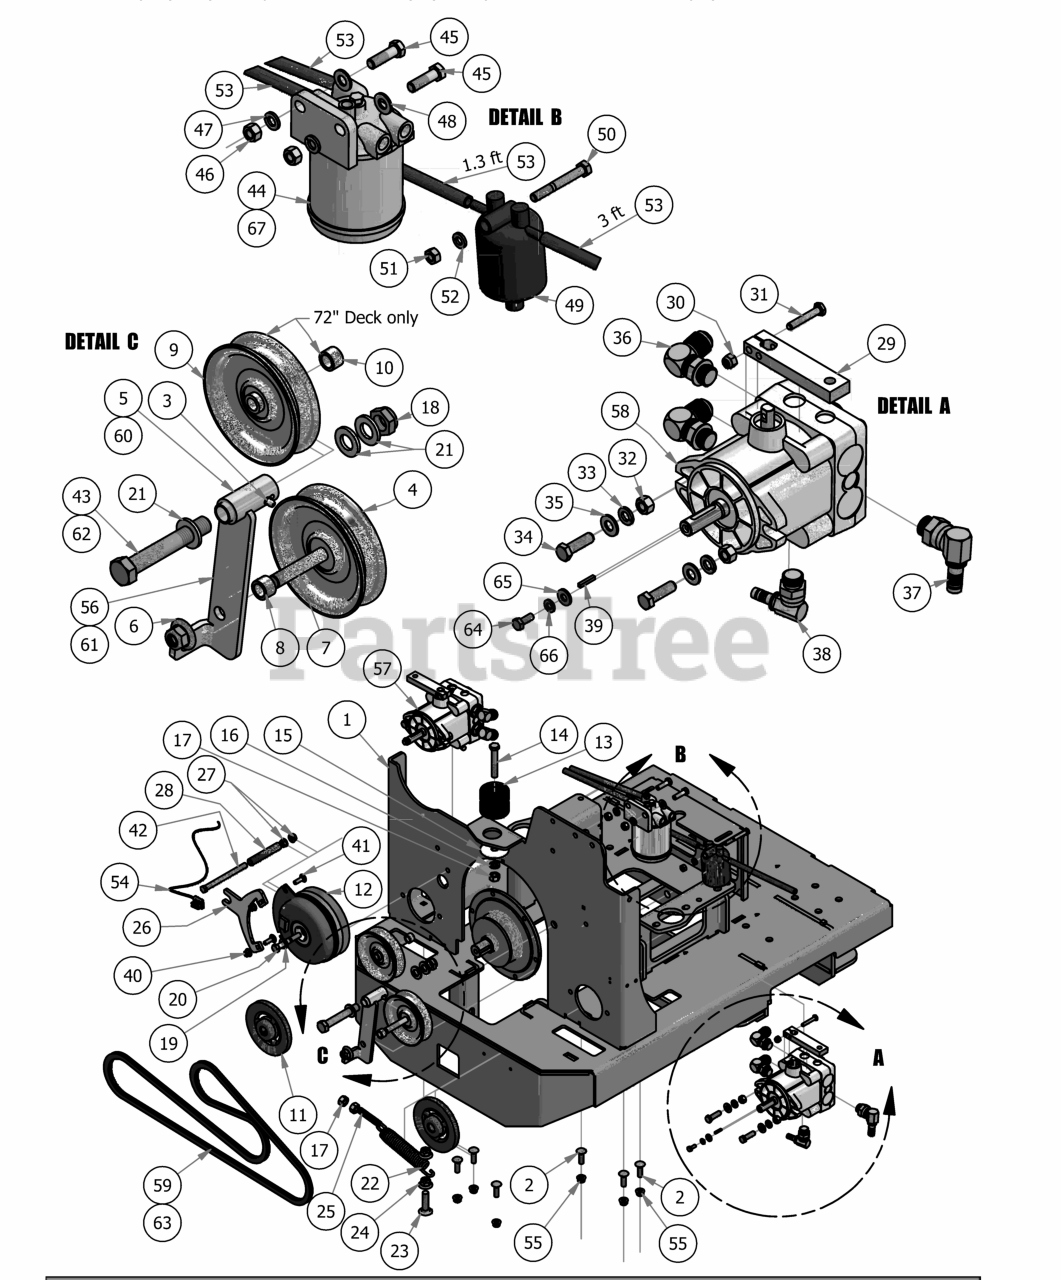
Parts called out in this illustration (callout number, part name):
1	Pump Plate Diesel
2	3/8" x 1 1/4" Carriage Bolt
3	1/4" Drive in Grease Fitting
4	4 3/4" Idler Pulley
5	Pump Idler Bracket only for 61" Deck
6	1/2-13 Nylon Flange Nut-Orange
7	1/2" x 3" Hex Bolt
8	1/2 x 1/2 Spacer
9	5" Idler Pulley only for 72" Deck Diesel
10	5/8" x 1/" Collar Spacer only for 72" Deck Diesel
11	5" Pump Pulley
12	Clutch Assembly for Diesel
13	Armor Plated Mount-Rear Mount
14	1/2" x 3" Hex Bolt
15	Snubbing Washer
16	1/2" Lock Washer
17	1/2" Hex Nut
18	5/8" Nylock (1/2 Jam)
19	7/16" Lock Washer
20	7/16" x 2 3/4" Fine Thread Bolt
21	.630 ID x 1.122 OD x .142 THK Plastic Washer
22	Deck Idler Spring
23	1/2 x 2" Carriage Bolt
24	1/2-13 Nylon Flange Nut-Orange
25	1/2-13 x 2-1/2 All Thd Stud
26	Diesel PTO Engager Holder
27	3/8" Flange Nut
28	3/8 hose 4" long
30	1/4" Nylock Nut
31	1/4" x 1 1/2" Bolt
32	3/8" Hex Nut
33	3/8" Lock Washer
34	3/8" x 1 1/2" Hex Bolt
35	3/8" Flat Washer
36	90 Degree Adaptor 6801-L-8-8 Fitting
37	90 Degree Fitting 1/2" x 3/4" 4601-8-8
38	90 Degree Fitting 3/8" X 9/16"- 4601-6-6
39	5mm x 1.25" Key
40	5/16" Flange Nut
41	5/16" x 1" Carriage Bolt
42	3/8-16 x 5 Hex Bolt - Grade 5
43	5/8" x 4" Hex Bolt 61" Deck only
44	CAT Fuel Filter
45	3/8" x 1 1/4" Hex Bolt
46	3/8" Hex Nut
47	3/8" Lock Washer
48	3/8" Flat Washer
49	Caterpillar Fuel Bowl Kit
50	5/16" x 2 1/2" Bolt
52	5/16" Lock Washer
53	5/16" fuel line hose
54	Clutch Pigtail
55	3/8" Nylock Flange Nut
56	Pump Idler Assembly Components 3,4,5,6,7,8, only for 61" Deck
57	Left Pump 16cc - AOS Diesel 35Hp Diesel
58	Right Pump 16cc - AOS Diesel 35Hp Diesel
59	Pump Belt for 72" Deck
60	Diesel Pump Idler only on 72" Deck
61	Diesel Pump Idler Assembly Components3,4,5,6,7,8,9,10 only for
62	5/8 x 5 1/2 Bolt only for 72" Deck
63	Pump Belt for 61" Deck
64	M6-1.0 X 16MM Hex Bolt
65	1/4" Flat Washer
66	1/4" Lock Washer
67	Perkins Fuel Filter
